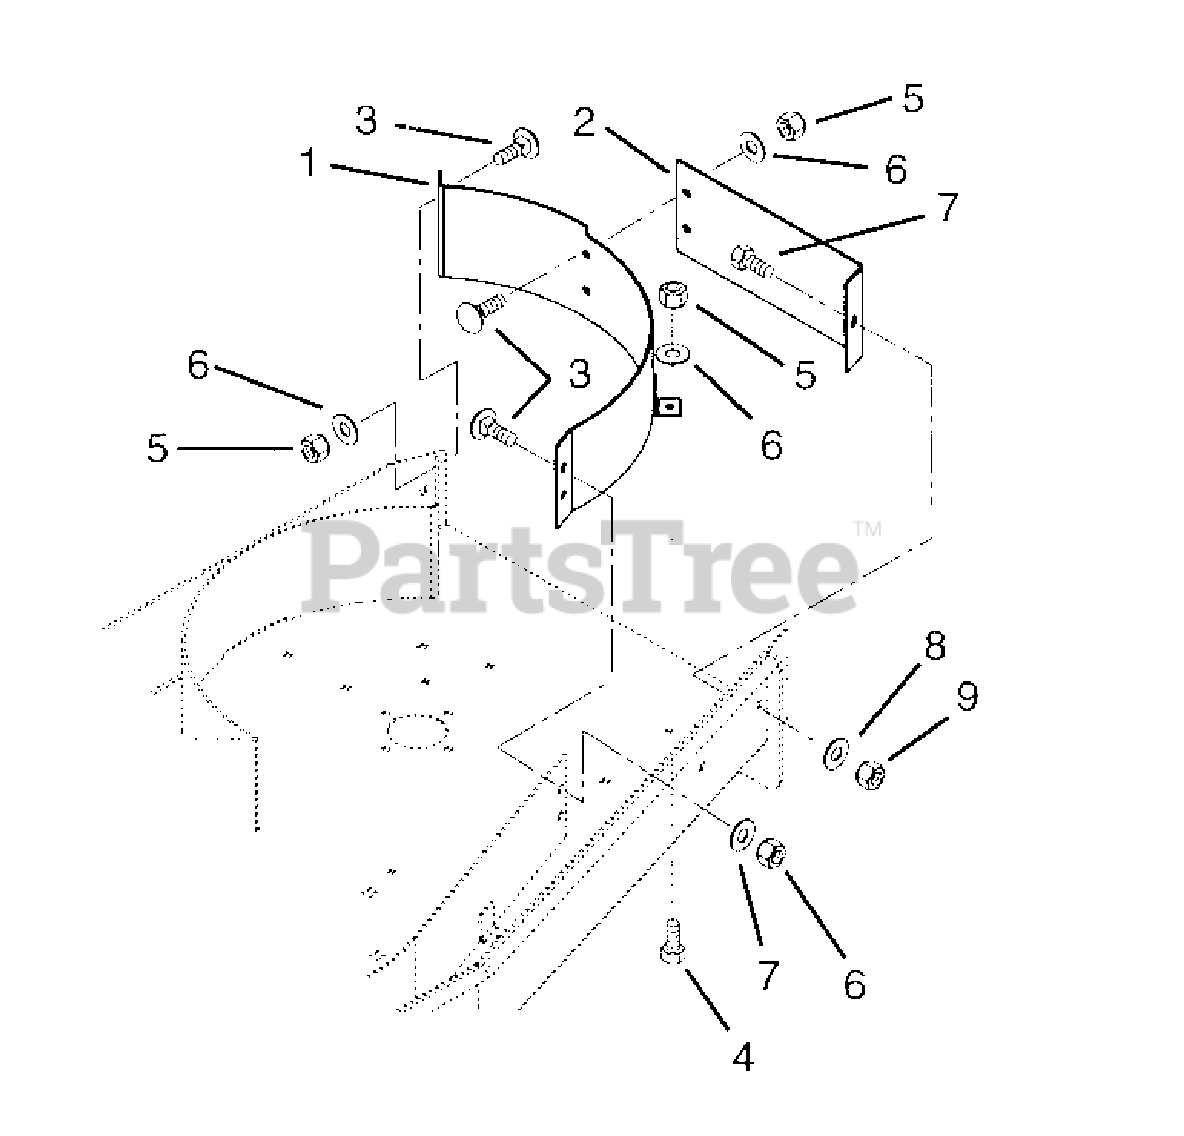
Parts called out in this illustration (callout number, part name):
1	Baffle, Weldment End
2	Baffle, End
3	Bolt, Round Head Square Shank .31-18 x .75
4	Bolt, Hex .31-18 x 1.00 Grade 5
5	Nut, Locking Nylon .31-18
6	Washer, Flat Steel .344 x .688 x .065
7	Bolt, Hex .38-16 x 1.00 Grade 5
8	Washer, Flat Steel .38 x .875 x .083
9	Nut, Locking Nylon .38-16
